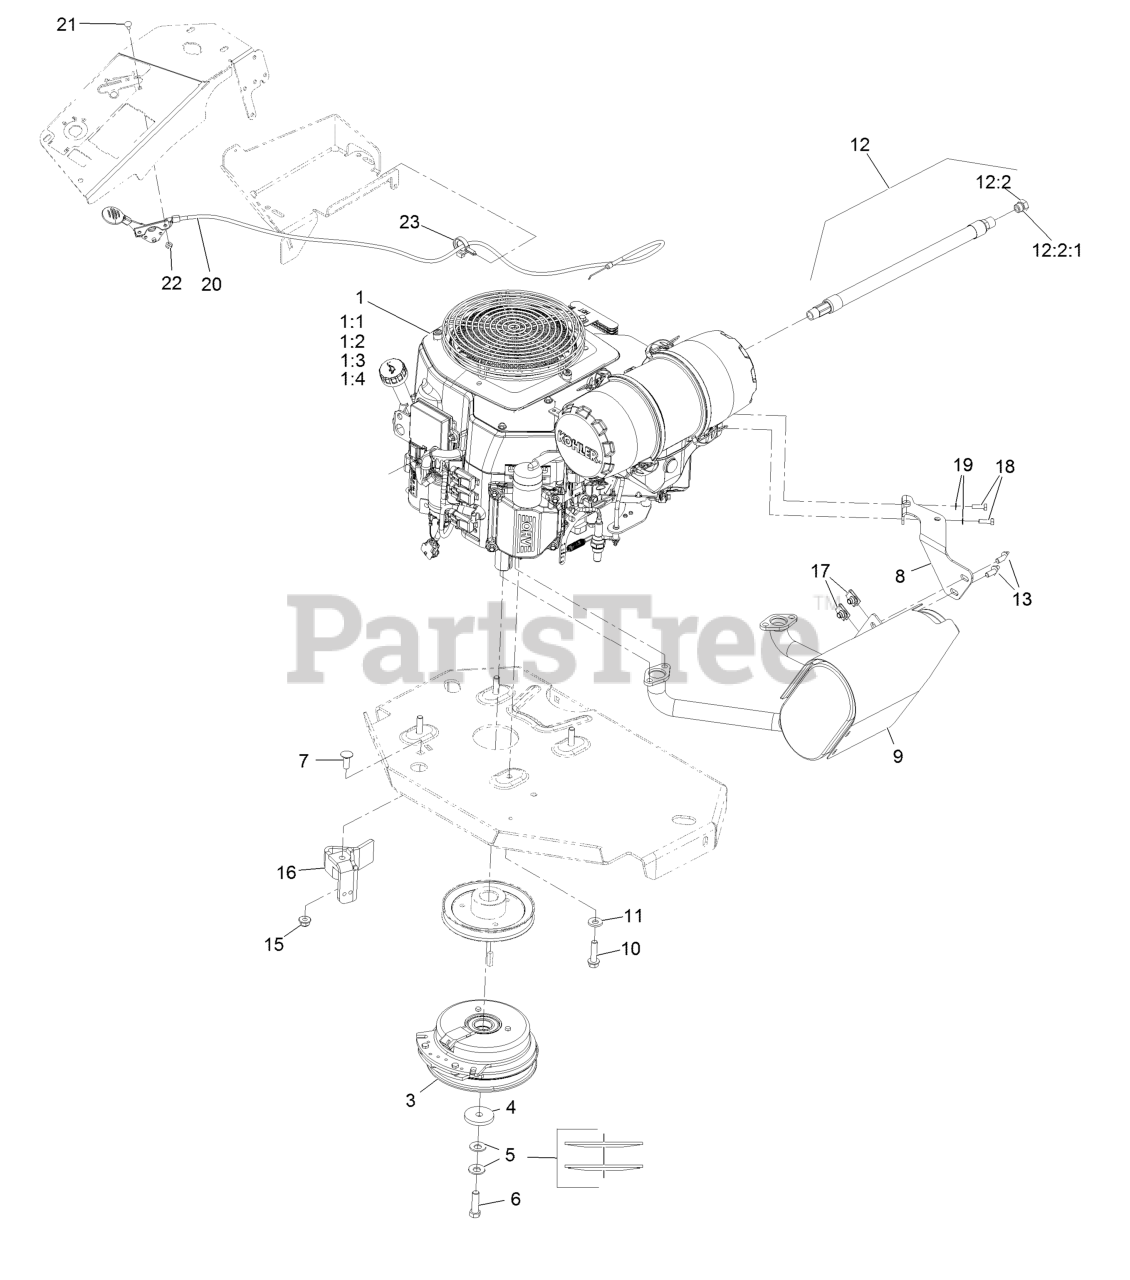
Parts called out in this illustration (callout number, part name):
1:1	Kohler 52 050 02-S Engine Oil Filter
1:2	Kohler 25 083 01-S Engine Air Filter
1:3	Kohler 25 083 04-S Safety Filter
1:4	Kohler 25 050 50-S Propane Fuel Filter
3	Clutch Kit
4	Washer-Clutch
5	Washer-Spring
6	Screw-HH
7	Screw-CARR
8	Muffler Bracket Kit
9	Muffler Kit
10	Screw-HWH
11	Washer-Belleville
12	Oil Drain Hose ASM
12:2	Plug-HH
12:2:1	O-Ring
13	Screw-HHF
15	Nut-HF, NI
16	Clutch-Anchor
18	Screw-HH
19	Washer-Spring
20	ASM,Throttle Cable
21	Bolt-CARR
22	Nut-Lock, NI
23	Clamp-Hose
